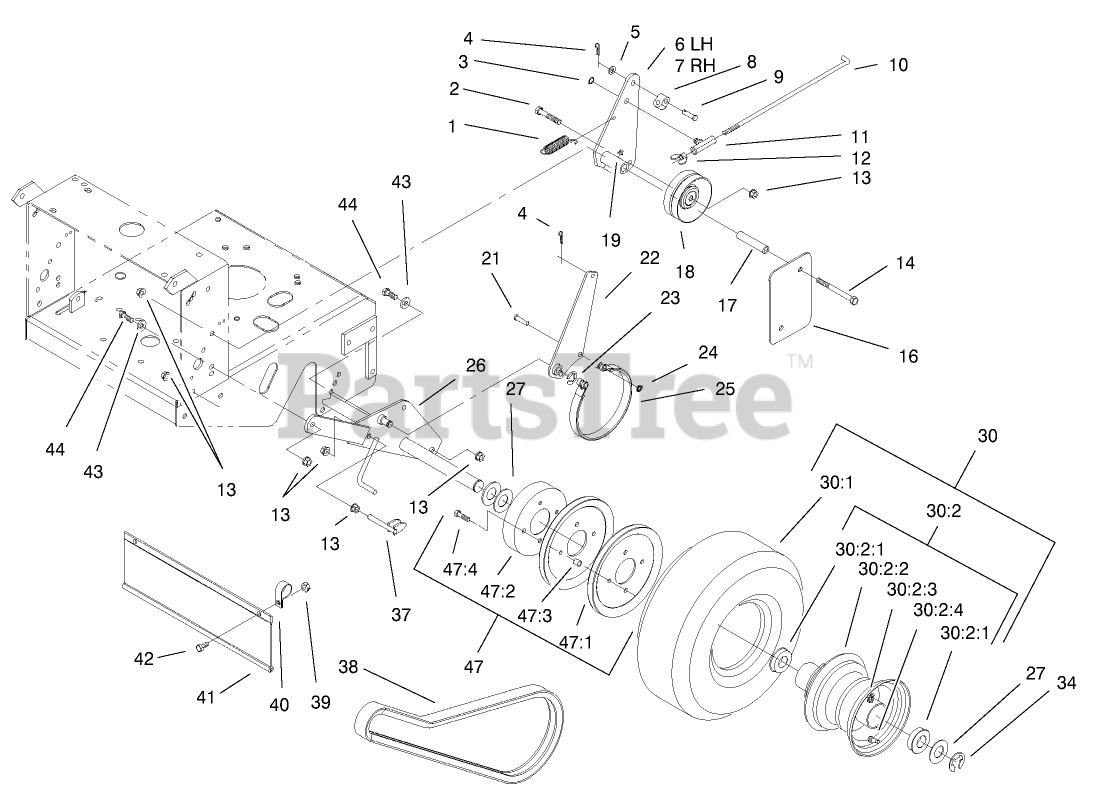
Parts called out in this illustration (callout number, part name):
1	SPRING-EXTENSION
2	SCREW-HH
3	RING-RETAINING
4	PIN-COTTER
5	WASHER-PLAIN
6	RH IDLER ARM ASM
7	LH IDLER ARM ASM
8	FITTING-ROD
9	PIN-CLEVIS
10	ROD-BRAKE
11	SWIVEL-BRAKE
12	WINGNUT-NYLOCK
13	NUT-HHF, WHIZ
14	SCREW-HH
16	SHIELD-WHEEL, DRIVE
17	SPACER-SHIELD
18	IDLER-DRIVE, WHEEL
19	FITTING-GREASE
21	PIN-CLEVIS
22	ARM-BRAKE
23	RING-RETAINING, EXTERNAL
24	NUT-PUSH
25	BAND-BRAKE
27	WASHER-SPACER
30	WHEEL AND TIRE ASM
30:1	Tire-Turfmaster
30:2	WHEEL AND HUB ASM
30:2:1	BEARING-FLANGED
30:2:2	Rim ASM
30:2:3	Fitting-Grease
30:2:4	Valve Stem
34	RING-SNAP
37	SCRAPER
38	V-BELT
39	NUT-LOCK, NI
40	CLAMP-R
41	SHIELD-TRAILING
42	SCREW-HH
43	WASHER-BELLEVILLE
44	SCREW-HH
47	Drum and Sheave ASM
47:1	SHEAVE-WHEEL, DRIVE
47:2	DRUM-BRAKE
47:3	SPACER-SHEAVE, WHEEL
47:4	SCREW-HH
